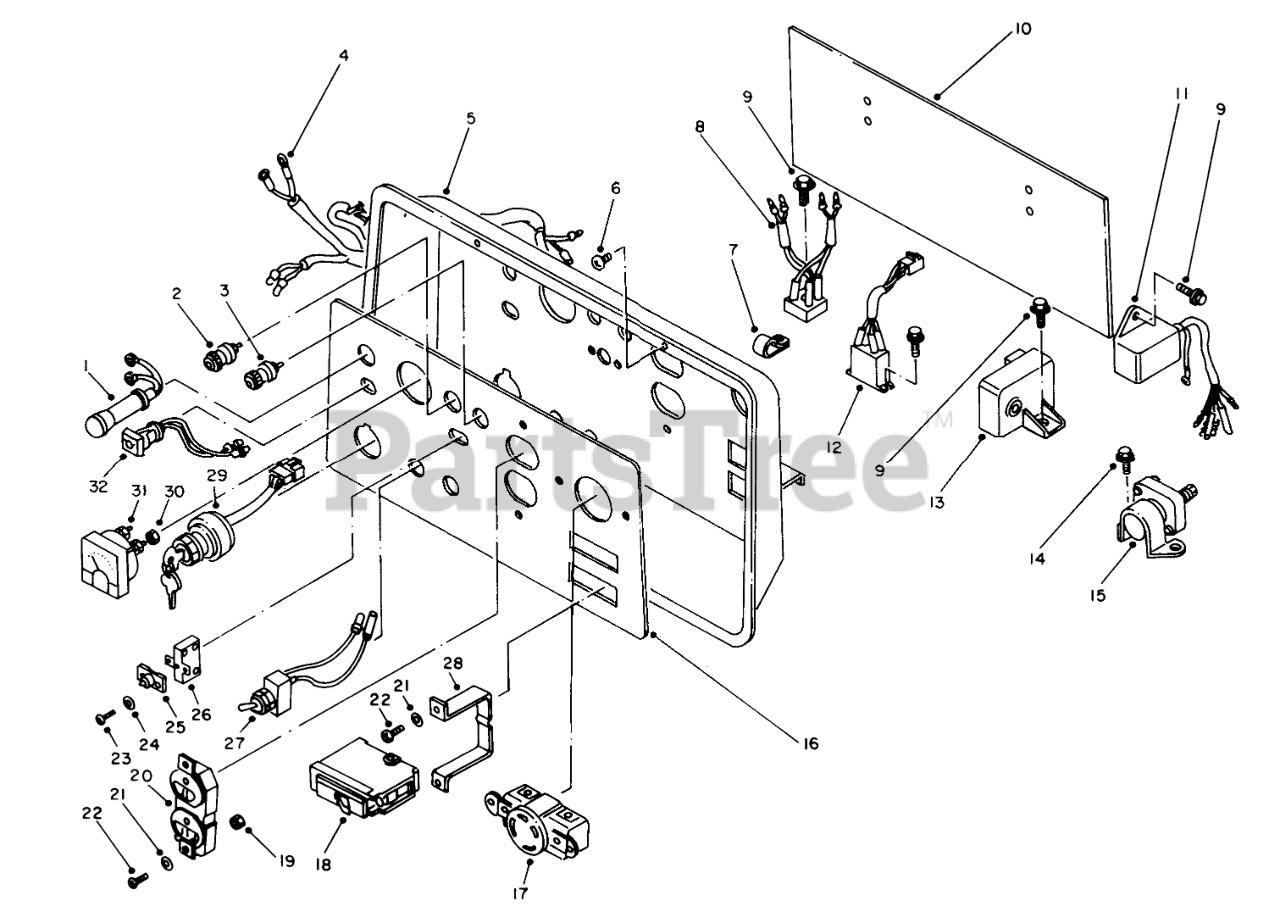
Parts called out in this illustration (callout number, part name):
1	Holder Assembly Lamp
2	TERMINAL (-)
3	Terminal
4	Wire Harness
5	Panel-Control
6	Screw
7	Clamp
8	RECTIFIER ASM
10	Insulato Panel
11	Unit-Fuel/Oil Interlock
12	Relay
13	Unit-Slow Down
14	SCREW-HHF
15	RELAY ASM
16	Plate-Panel
17	Receptacle
18	CIRCUIT BREAKER
20	Receptacle
21	Washer
22	Screw
23	Screw
24	Washer
26	Protector-Circuit
27	Switch
28	Holder-Breaker
29	Switch-Engine
31	Voltage Meter
32	Lamp-Oil Level
